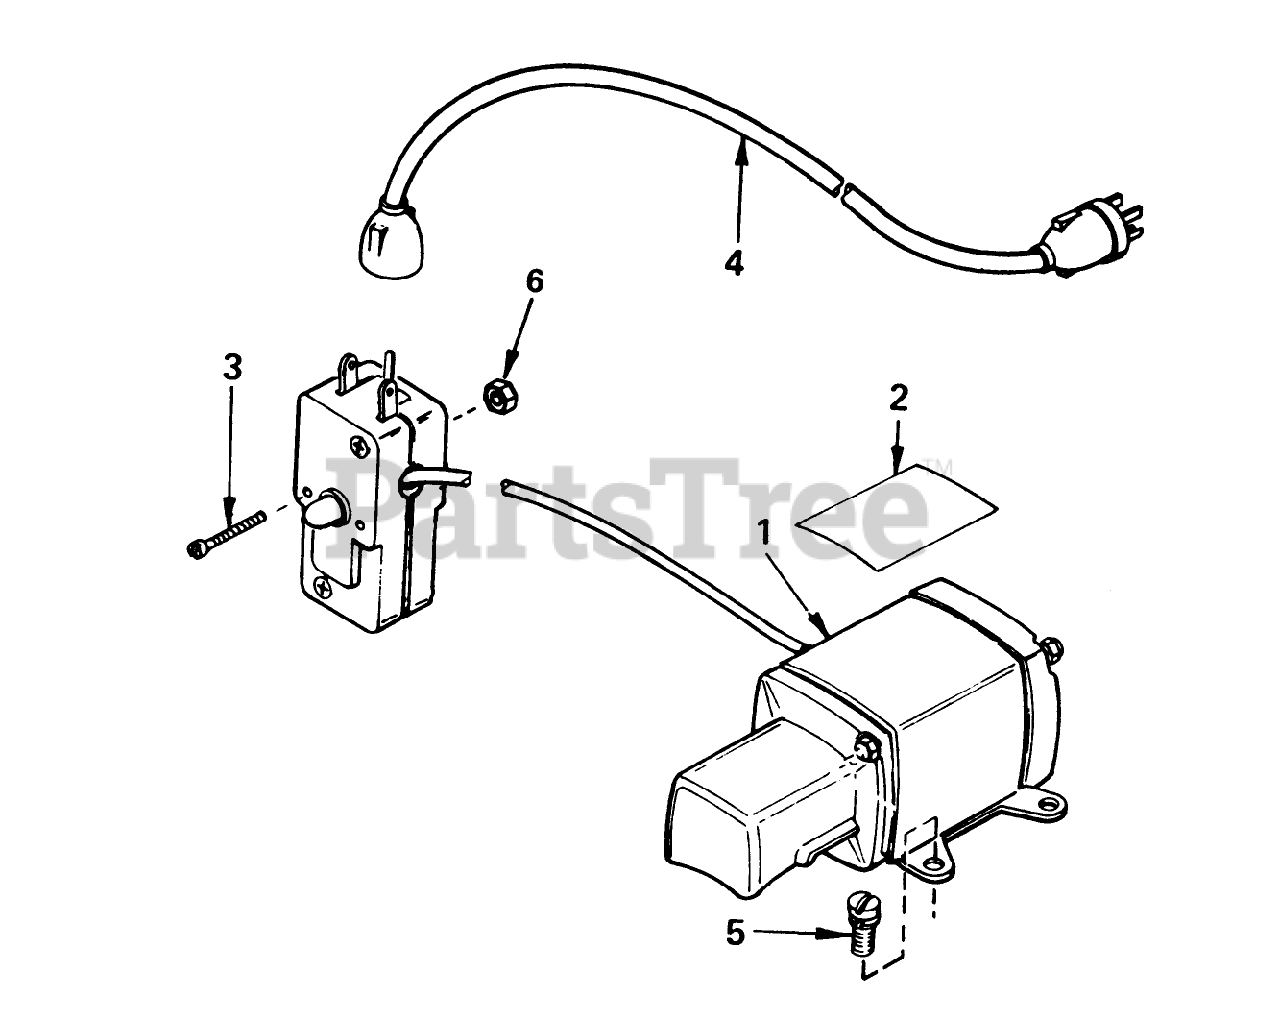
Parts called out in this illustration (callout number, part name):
1	Motor, Cranking (CSA Approved) (Incl. #2 thru 6)
2	Decal
3	Screw, Pan Hd.
4	Cord-Extension
5	Screw (T-30, 1/4-20 x 23/32)
6	Nut Lockwasher
